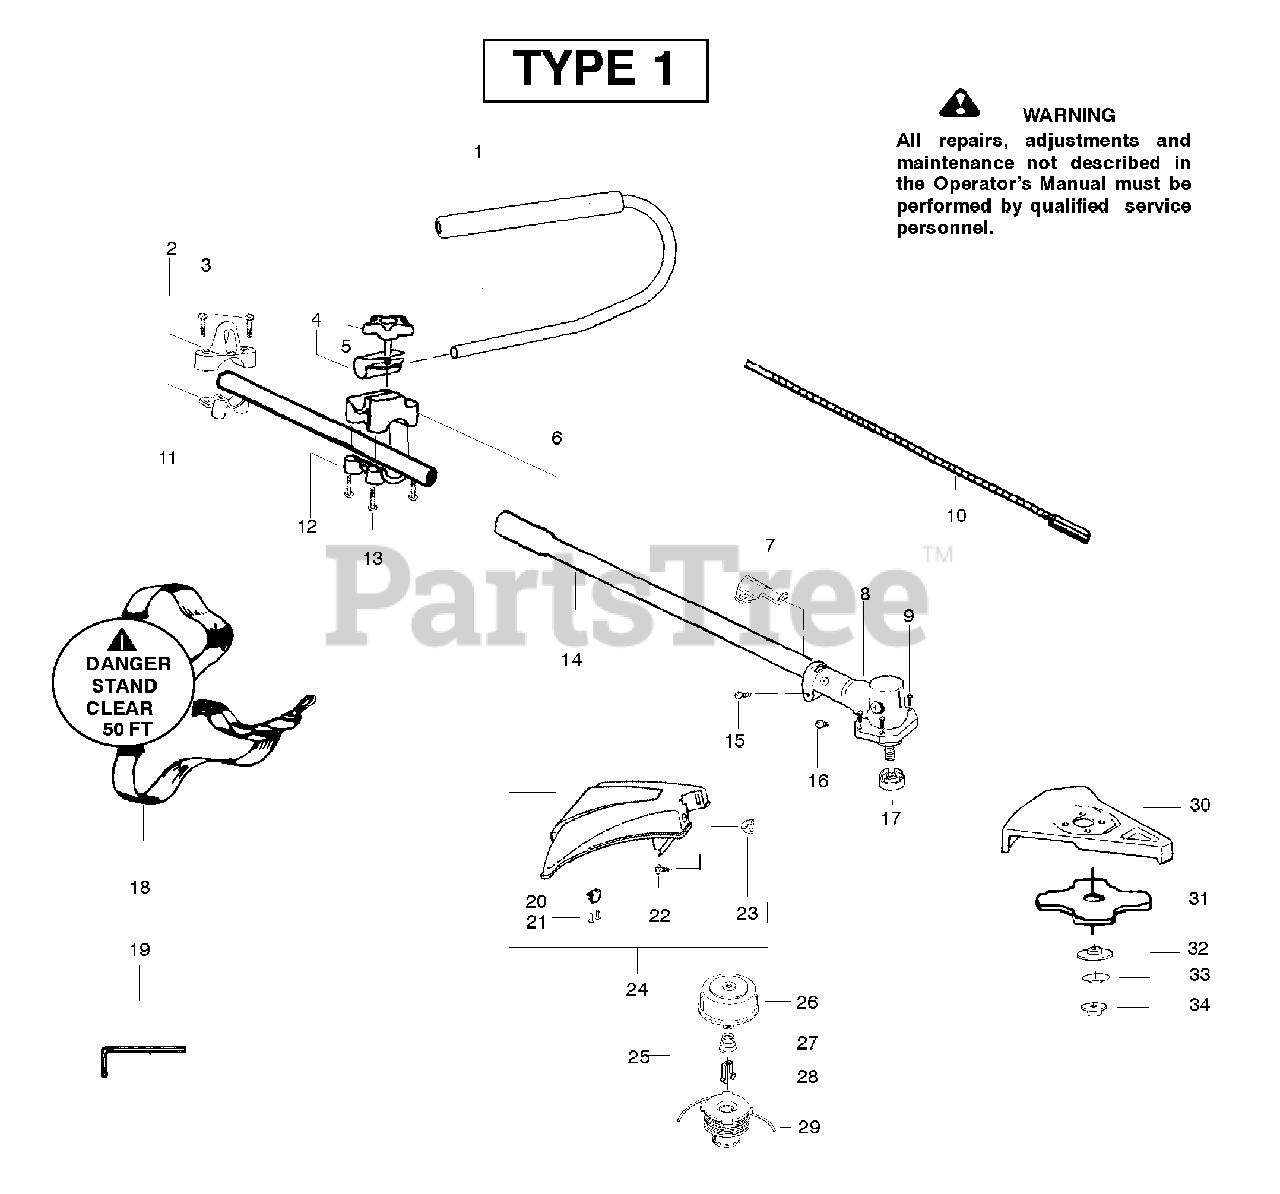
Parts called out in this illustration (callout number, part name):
1	Kit-Handlebar
2	Clamp-Harness Upper
4	Clamp-Handlebar
5	Knob
6	Base-Clamp
7	Bracket-Shield
8	Assy-Gearbox
10	Flexshaft-Split boom
11	Clamp-Harness Lower
12	Kit-Clamp-Tube
14	Assy.-Driveshaft
16	Screw-Alignment
17	Dust cup - Blade
18	Assy-Shoulder Strap
19	Wrench-Hex (5/32")
20	Limiter-Line
21	Screw
23	Wingnut
24	Kit-Shield
25	Accy-Cutting Head
26	Assy-Hub
28	Retainer
29	Accy-Spool
30	Kit-Blade Shield
31	Accy.-Weed Blade (8")
32	Washer-Blade Retaining
33	Washer-Belleville
34	Nut-Flange
